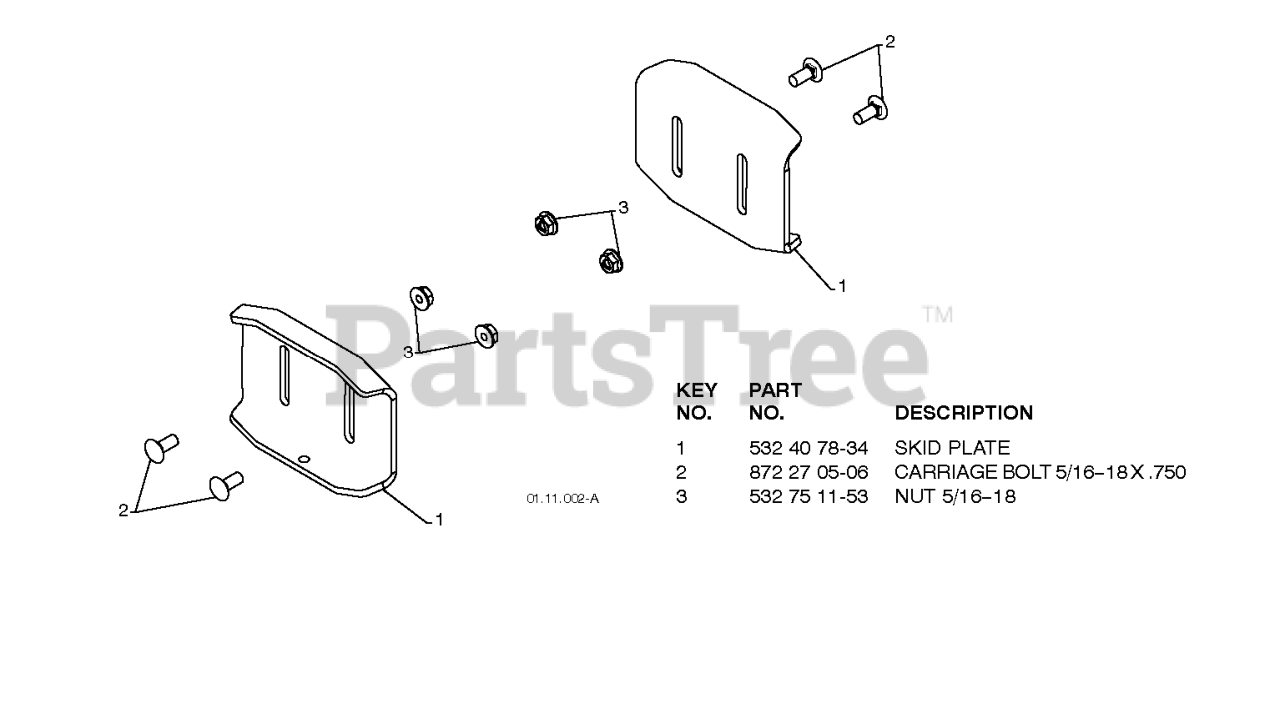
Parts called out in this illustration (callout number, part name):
1	SKID PLATE
2	BOLT
3	NUT.LOCK.5/16-18
